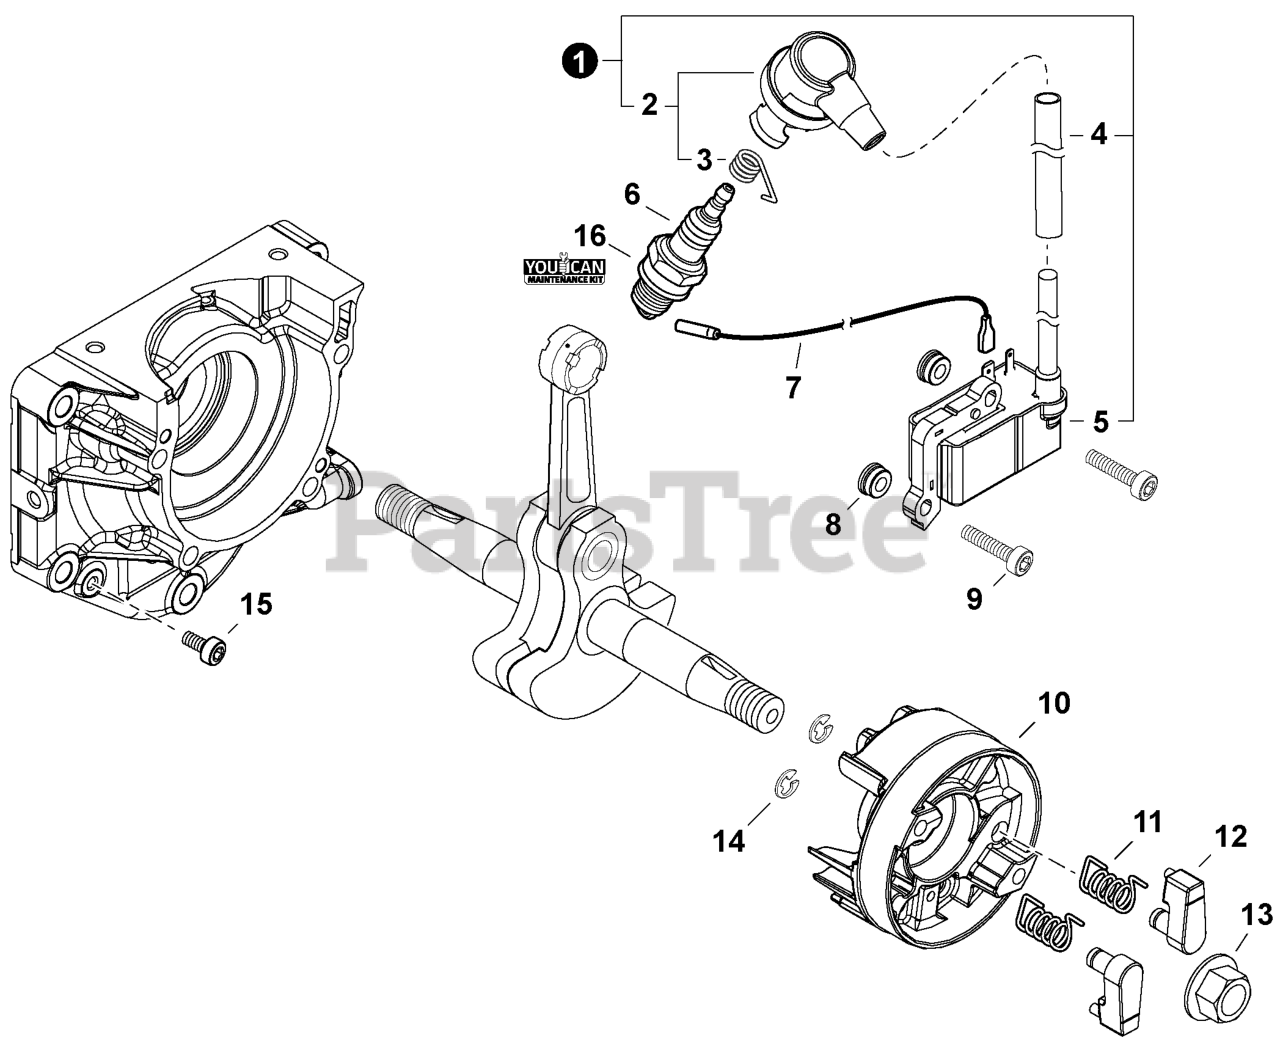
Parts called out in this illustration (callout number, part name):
1	COIL ASSY, IGNITION
2	CAP ASSY, SPARK PLUG
3	TERMINAL, SPARK PLUG
4	TUBE, INSULATOR
5	COIL, IGNITION
6	SPARK PLUG - CMR7H
7	LEAD - IGNITION
8	COLLAR 4
9	BOLT 4x20
10	FLYWHEEL
11	SPRING, RETURN
12	PAWL, STARTER
13	NUT, FLANGE 10x1.25
15	BOLT, TORX 4x10
16	TUNE-UP KIT - YOUCANT
